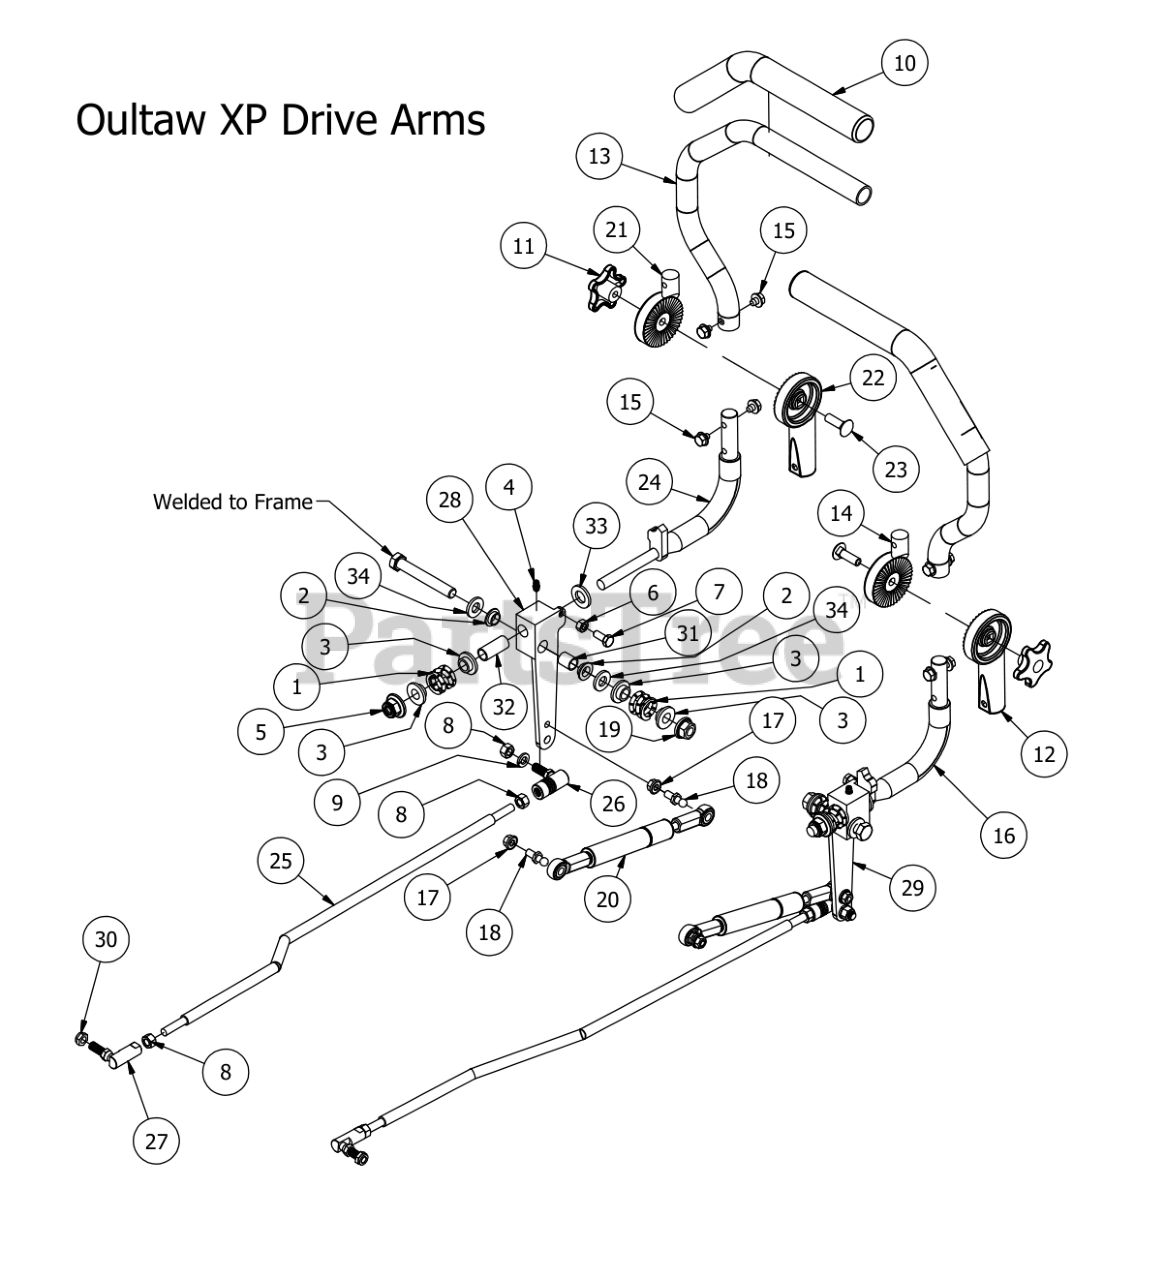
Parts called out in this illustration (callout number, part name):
1	Drive Lever Spring
2	Bushing for 2012 Drive Arms
3	.515 ID Nylon Shoulder Washer
4	1/4" Press in Grease Fitting
5	1/2-13 Nylon Flange Nut
7	5/16" x 3/4" Hex Bolt
8	3/8" Fine Threaded Jam Nut
9	3/8" Lock Washer
10	Black Steering Grip
11	Black Knob for Adjustable Steering Arm
12	Lower Adjuster - Steering Arm- Right
13	Upper Tube-Adjustable Steering
14	Upper Adjust Steering Arm- Right
15	5/16-18 1/2 HWH Bolt-Steering
16	Steering Arm Elbow - Right
17	5/16" Flange Nut
18	10mm Damper Ball Stud-Steering
19	1/2-13 Mechanical Lock Nut Grade F
20	Steering Damper
21	Upper adjuster-Steering Arm- Left
22	Lower Adjuster - Steering Arm- Left
23	3/8" x 1 1/4" Carriage Bolt
24	Steering Arm Elbow - Left
25	outlaw XP Push Rod
26	Quick Release Ball Joint
27	3/8-24 Ball Joint
28	Drive Arm Lever Housing (Left)
29	Drive Arm Lever Housing Right
30	3/8-24 Nylon Insert jam locknut
31	Drive Arm Block Insert-short
32	Drive Arm Block Insert-long
33	.630 ID Plastic Washer
34	.505x1x .125 Oil Impregnated washer
